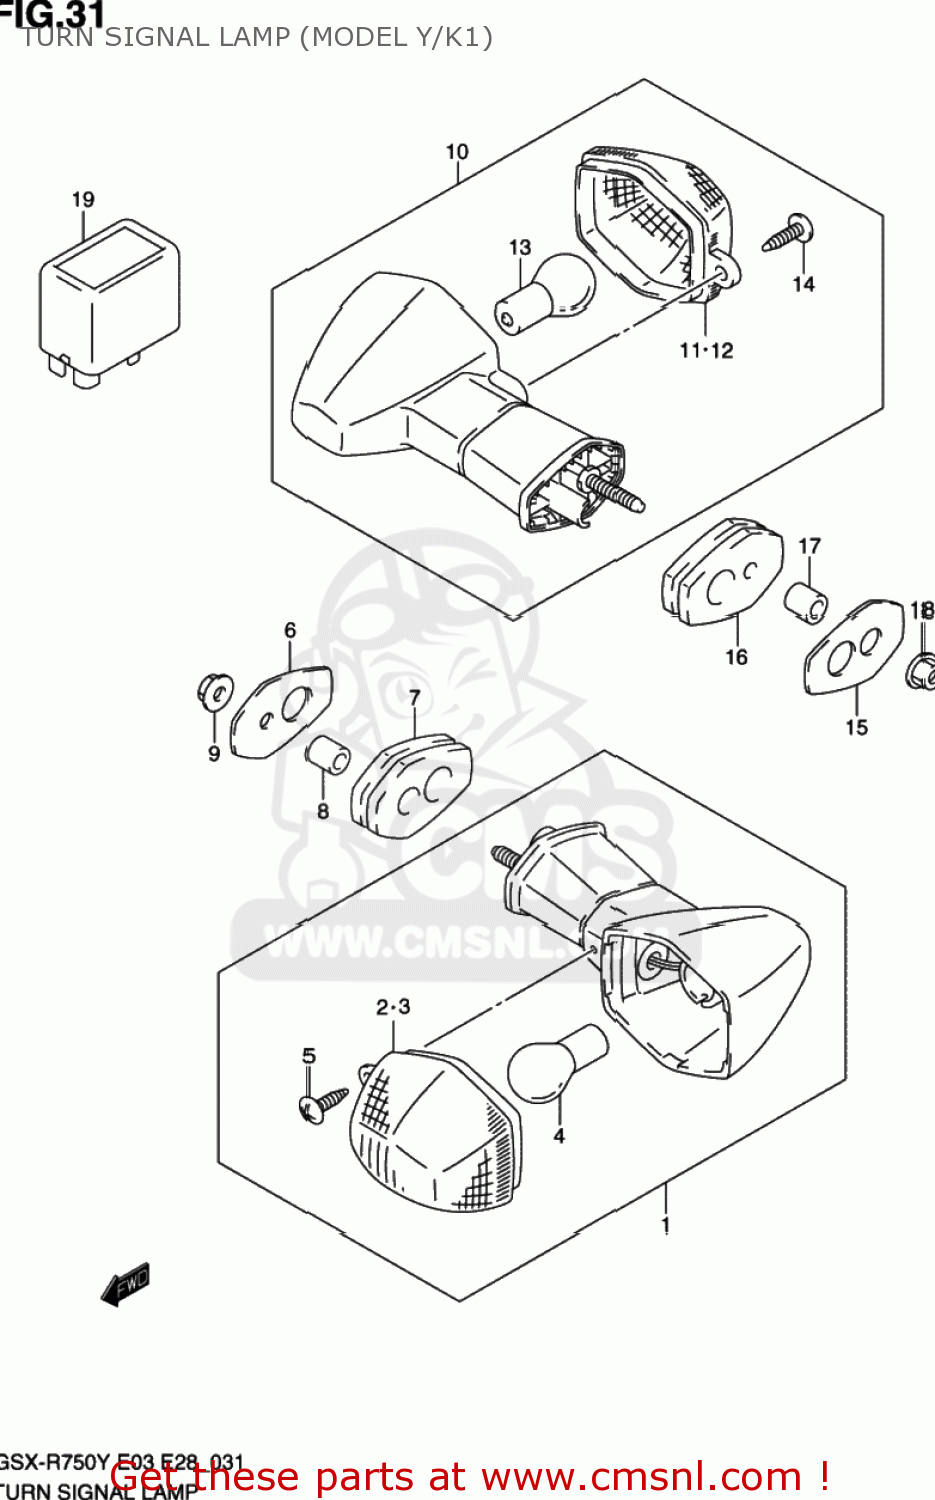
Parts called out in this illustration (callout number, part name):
1	LAMP ASSY,FR TURN SIGNAL,R
2	LENS
3	LENS
4	BULB(12V21W)
5	SCREW
6	PLATE,FR TURNSIGNAL
7	CUSHION,FR TURNSIGNAL
8	SPACER(5.5X9.5X10)
9	NUT
10	LAMP ASSY,RR TURNSIGNAL,R
11	LENS
12	LENS
13	BULB(12V21W)
14	SCREW
15	PLATE,FR TURNSIGNAL
16	CUSHION,FR TURNSIGNAL
17	SPACER(5.5X9.5X10)
18	NUT
19	RELAY ASSY,TURNSIGNAL LAMP
